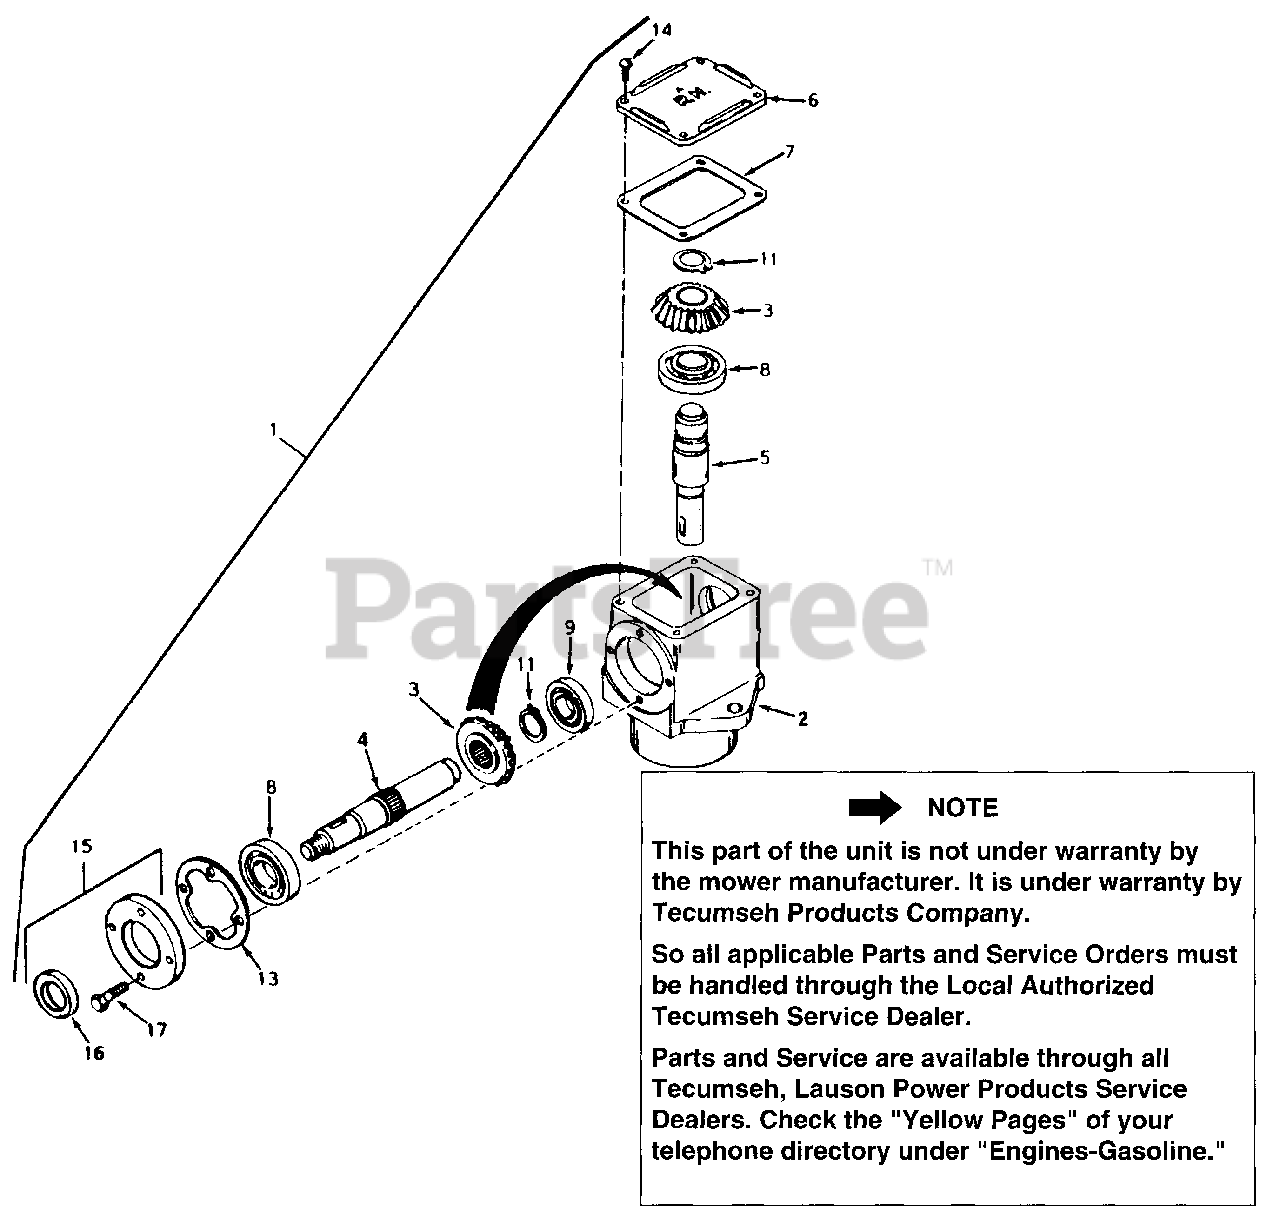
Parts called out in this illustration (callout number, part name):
1	Head Assembly R.H.
2	Housing, Right Angle Drive
3	Gear, Miter
4	Shaft, Input
5	Shaft, Output
6	Cover, Right Hand
7	Gasket, Cover
8	Bearing, Ball
9	Bearing, Ball
11	Ring, Snap
13	Gasket, Cap
14	Screw, Rd. Hd. Self-Tap. 10-24 x 1/2
15	Cap & Seal Assembly, Retainer
16	Seal, Oil
17	Screw, Hex Hd. 1/4-20 x 7/8
